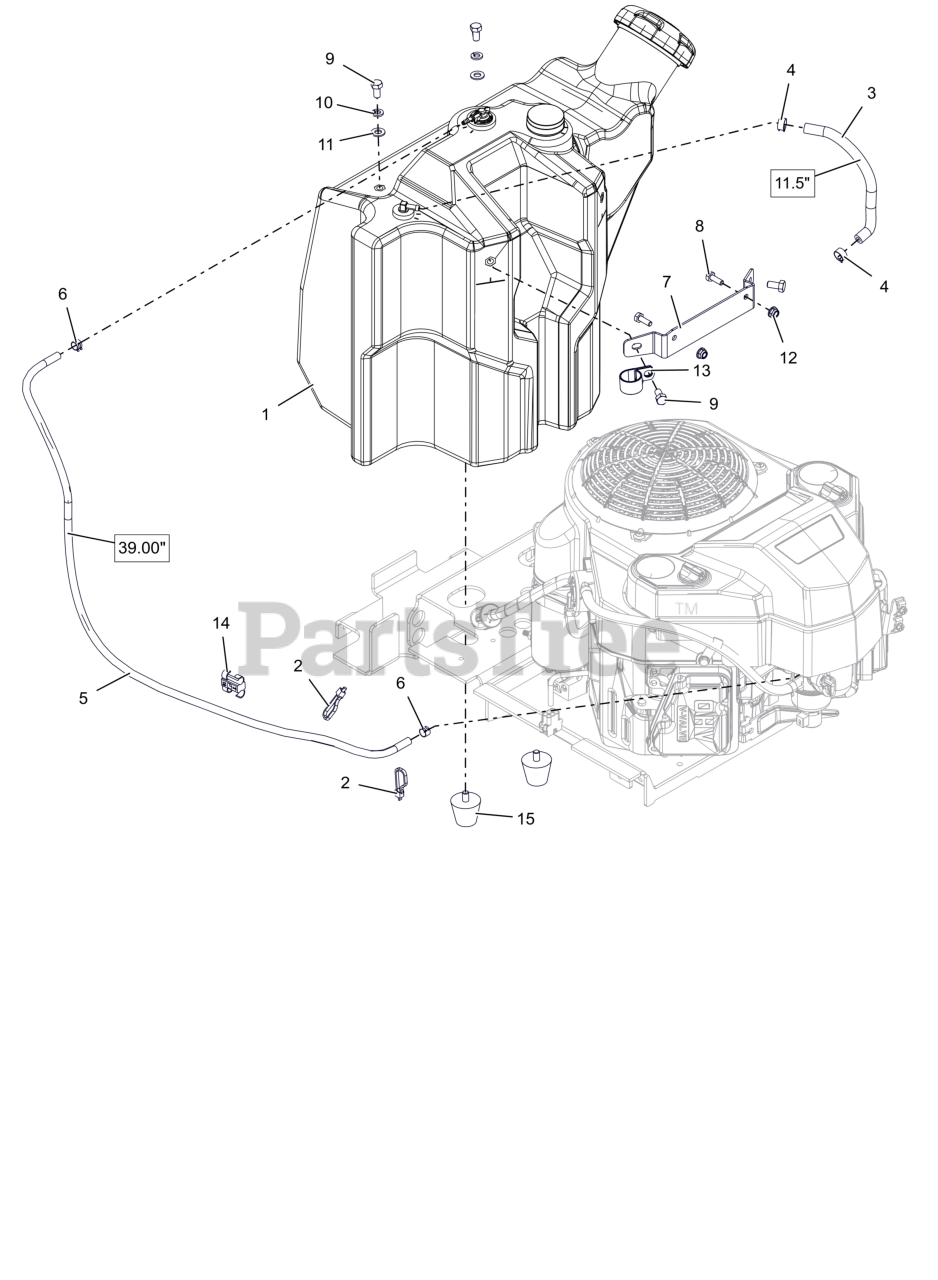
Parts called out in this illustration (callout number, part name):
1	ASM, 32-36" PROSTANCE FUEL TANK
2	CABLE TIE, .15 X 8.50
3	HOSE, .25 LOW-PERM BULK GAS
4	CLAMP, FUEL LINE
5	HOSE, .188 LOW-PERM BULK GAS
6	CLAMP-HOSE, SPRING .188
7	BRKT, OVERFLOW MTG (BLACK)
8	BLT, HEX .25-20X.75 G5 ZCC
9	BLT, HEX .31-18X.625 G5 ZCC
10	WSHR,LK-REG .312X.078 ZCC
11	WSHR,FLT .344X.688X.065 ZCC
12	NUT,NYL-FLG .25-20 GF ZCC
13	CLAMP, COUSHIONED STEEL REV
14	CLIP, T, .38-.50
15	BUMPER, STUD MOUNTED CONE SHAPED
